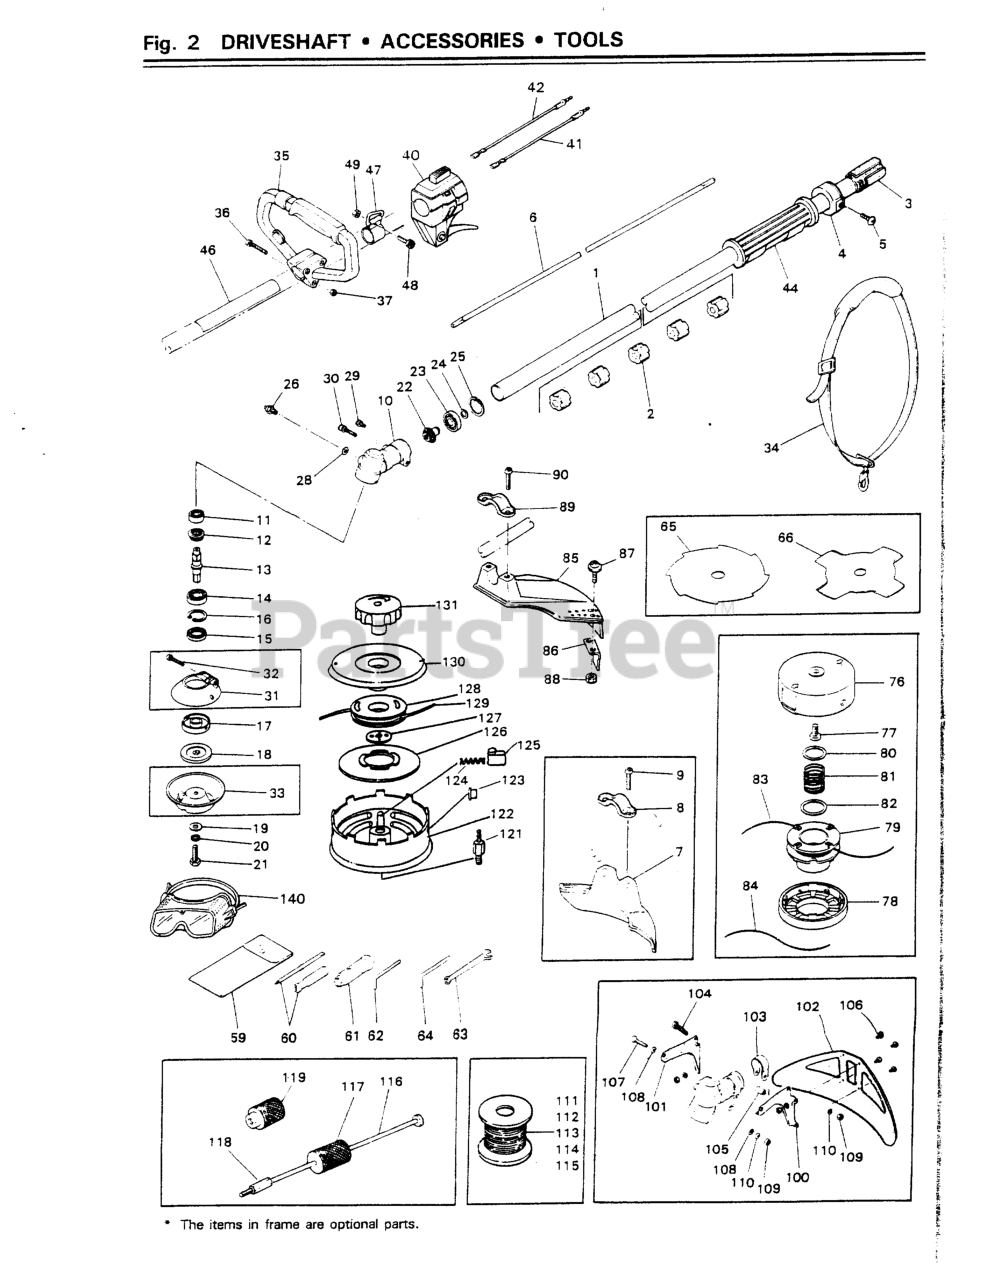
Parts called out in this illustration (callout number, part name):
4	CAP
5	SCREW, M5 X 10
6	SHAFT (NLA)
8	CLAMP (REPLACES 5807-24120)
9	BOLT, M6 x 1.30
12	GEAR
14	BEARING (RPLS T3403-13510)
15	SEAL, OIL
16	RING, SNAP, M26 X 1.2
17	HOLDER (A) (NLA)
18	HOLDER (B)
19	WASHER
20	WASHER
21	BOLT
23	BEARING (RPLS T3300-13531)
24	RING, SNAP (RPLS T3300-13330)
25	RING, SNAP, M24 x 1.2
26	FITTING, GREASE
28	WASHER, M6 X .8
29	BOLT, M5 X 10
30	BOLT
31	COVER (USE -13402)
32	SCREW, M4x25 (RPLS.0260-30425)
35	HANDLE ASSEMBLY (NLA)
36	SCREW, M5 x 30(RPLS 0263-00530
37	NUT, M5 X 4
41	CORD-A, BLACK
42	CORD-B, RED
46	PLATE, NAME
47	HANGER COMP
48	BOLT, M5 X 10
49	NUT, M5 X 4
60	SCREWDRIVER
62	WRENCH (TOOL)
63	SPANNER, 8 X 10 (RPLS 2540- )
64	BAR
77	SHAFT (D)
80	PLATE, LARGE
82	PLATE, SMALL
86	BLADE
87	SCREW, M5 x 12
88	NUT
89	CLAMP (REPLACES 5807-24120)
90	BOLT, M6 x 1.30
100	BRACKET (A)
102	GUARD (NLA)
103	CLAMP (NO LONGER AVAILABLE)
104	BOLT, M5 X 30
108	WASHER, M5x.8(RPLS 01624-20508
109	NUT, M5 X 4
110	WASHER, SPRING M4 x 1.3
116	SHAFT (TOOL)
119	BLOCK (TOOL)
121	ADAPTER-MALE
122	HOUSING, SPOOL
123	EYELET (RPLS -15220)
124	SPRING, RED
125	SLIDE CAM (1 PC)
126	CAM DISK
127	NUT, FLAT
NI	FULL-AUTO HEAD
NI	LEVER ASSEMBLY
